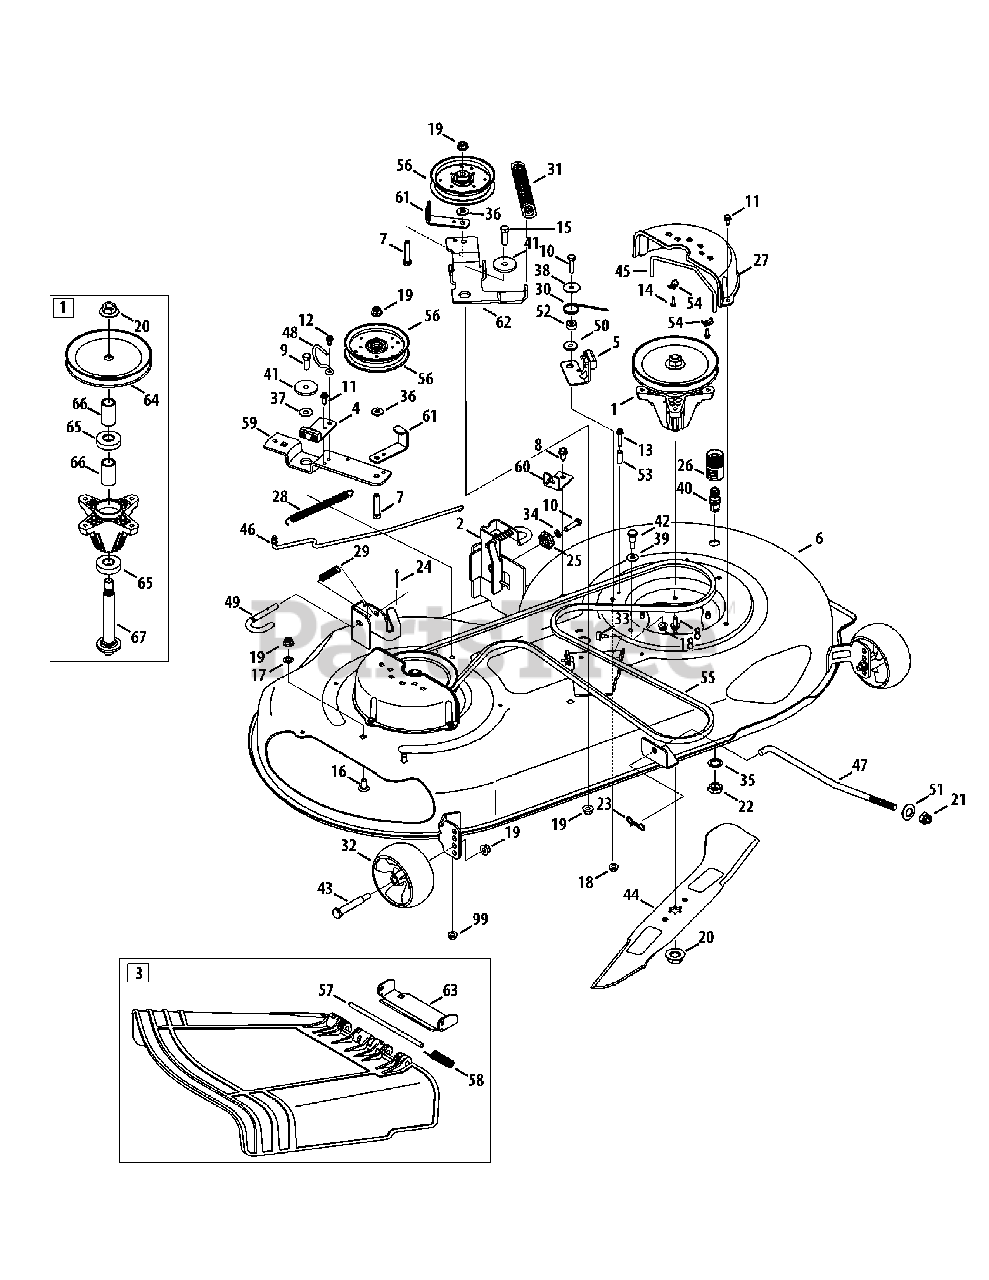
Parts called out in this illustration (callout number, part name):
1	Spindle Assembly
2	Deck Hanger Bracket Assembly
3	Chute Deflector Assembly
4	Brake Assembly
5	Brake Assembly
6	Deck Asm 46t 2w
7	Screw 3/8-16 1.75 Gr5 Std
8	Tap Screw, Ind. Washer, 5/16-18 .750
9	Hex Head Screw, 3/8-16 1.00
10	Hex Head Screw, 5/16-18 1.25
11	Tap Screw, Ind. Washer, 1/4-20 0.500
12	Screw, 1/4-20 x .750
13	Screw, 1/4-20 x 1.50
14	Screw, #10-16
15	Screw 3/8-16 1.25 Gr5 Std
16	Carriage Bolt, 3/8-16 0.75
17	Push Nut, 3/8
18	Nut, Flange Lock Nut, 5/16-18
19	Flangelock Nut, 3/8-16
20	Flange Nut, 5/8-18
21	Lock Nut, 1/2-13
22	Hex Nut, M16-1.5 DIN 936
23	Bow-Tie Cotter Pin
24	Cotter Pin, 1/8 X 1.25
26	Water Nozzle Adaptor
26	Plug, Deck Wash
27	Belt Cover
28	Extension Spring, .62 DIA. X 6.12 LG
29	Compression Spring, .535 OD X 1.751 LG
30	Torsion Spring, .992 x 1.17
31	Spring, Extn 1.00 X 7.11 75 X .183
32	Front Deck Wheel
33	Bumper .62 Dia X .3
34	Lock Washer, 5/16
35	Lock Washer, 5/8
36	Flat Washer, .385 X .870 X .092
37	Flat Washer, .385 X 1.0 X .030
38	Flat Washer, .330 X 1.25 X .06
39	Washer Flat .343 X .880 X .062
40	Deck Water Nozzle
40	Washer,Flat .64 x 1.24 x .06
41	Shoulder Spacer, .8840 X .190
42	Screw Shld .437 Dia. X .54
43	Shoulder Bolt, .496 X 2.50 3/8-16
44	2-in-1 Cutting Blade
45	Belt Keeper Rod
46	Brake Rod
47	Deck Lift Rod
48	Belt Keeper Rod
49	Deck Release Handle Rod
50	Shoulder Spacer
51	Deck Lift Pivot Cup
53	Spacer, .260 X .375 X 1.030 Lg
54	Casing Clamp
56	Idler Pulley, 4.25"DIA
58	Torsion Spring
59	Idler Bracket
60	Deck Engage Cable Bracket
61	4.25 Pulley Belt Guard Bracket
62	Bracket Idler 46" LH
63	Chute Bracket
64	Deck Pulley, 6.93 DIA
65	Ball Bearing, .787ID X 1.85 OD X .551
66	Spacer, .792 X 1.060 X 1.860 LG
67	Spindle Shaft, 6.05 LG.
